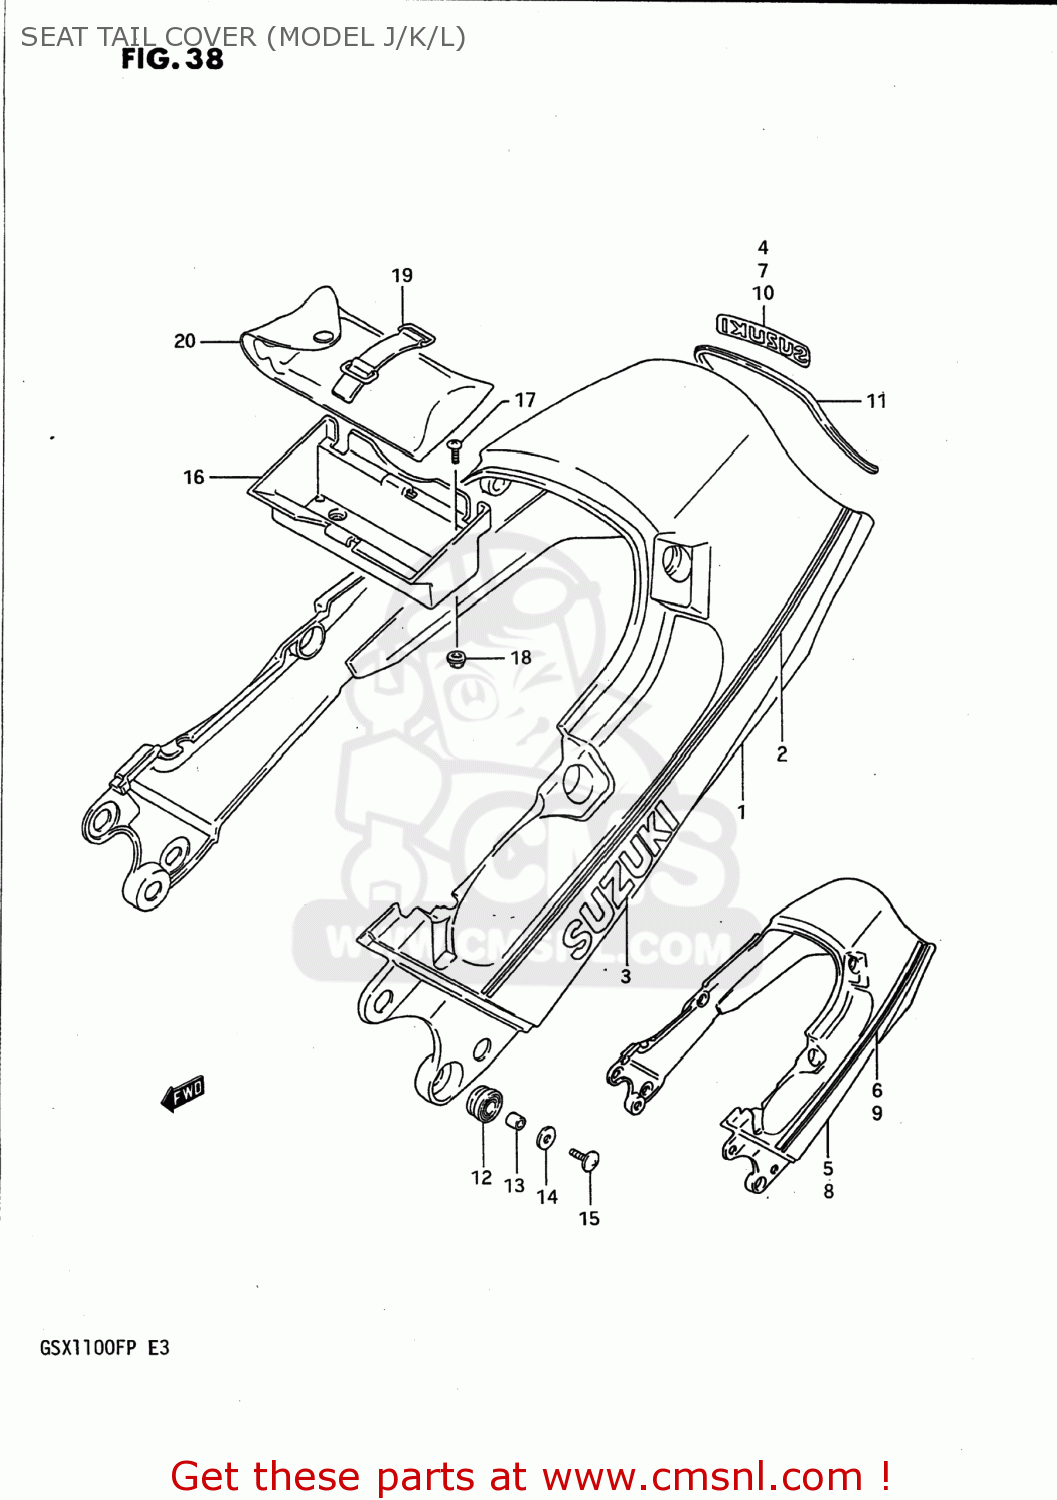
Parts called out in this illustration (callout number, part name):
1	COVER SET,SEAT TAIL
2	TAPE SET,SEAT TAIL COVER
3	EMBLEM
4	EMBLEM
5	COVER SET,SEAT TAIL
6	TAPE SET,SEAT TAIL COVER
7	EMBLEM
8	COVER SET,SEAT TAIL
9	TAPE SET,SEAT TAIL
10	EMBLEM
11	MOLDING,SEAT TAIL COVER
12	CUSHION,SEAT TAIL COVER SIDE
13	SPACER (6.1X8X8)
14	WASHER(6,5X22X1.6)
15	SCREW, CENTER
16	HOLDER,TOOL
17	SCREW
18	NUT
19	BAND
20	TOOL ASSY
